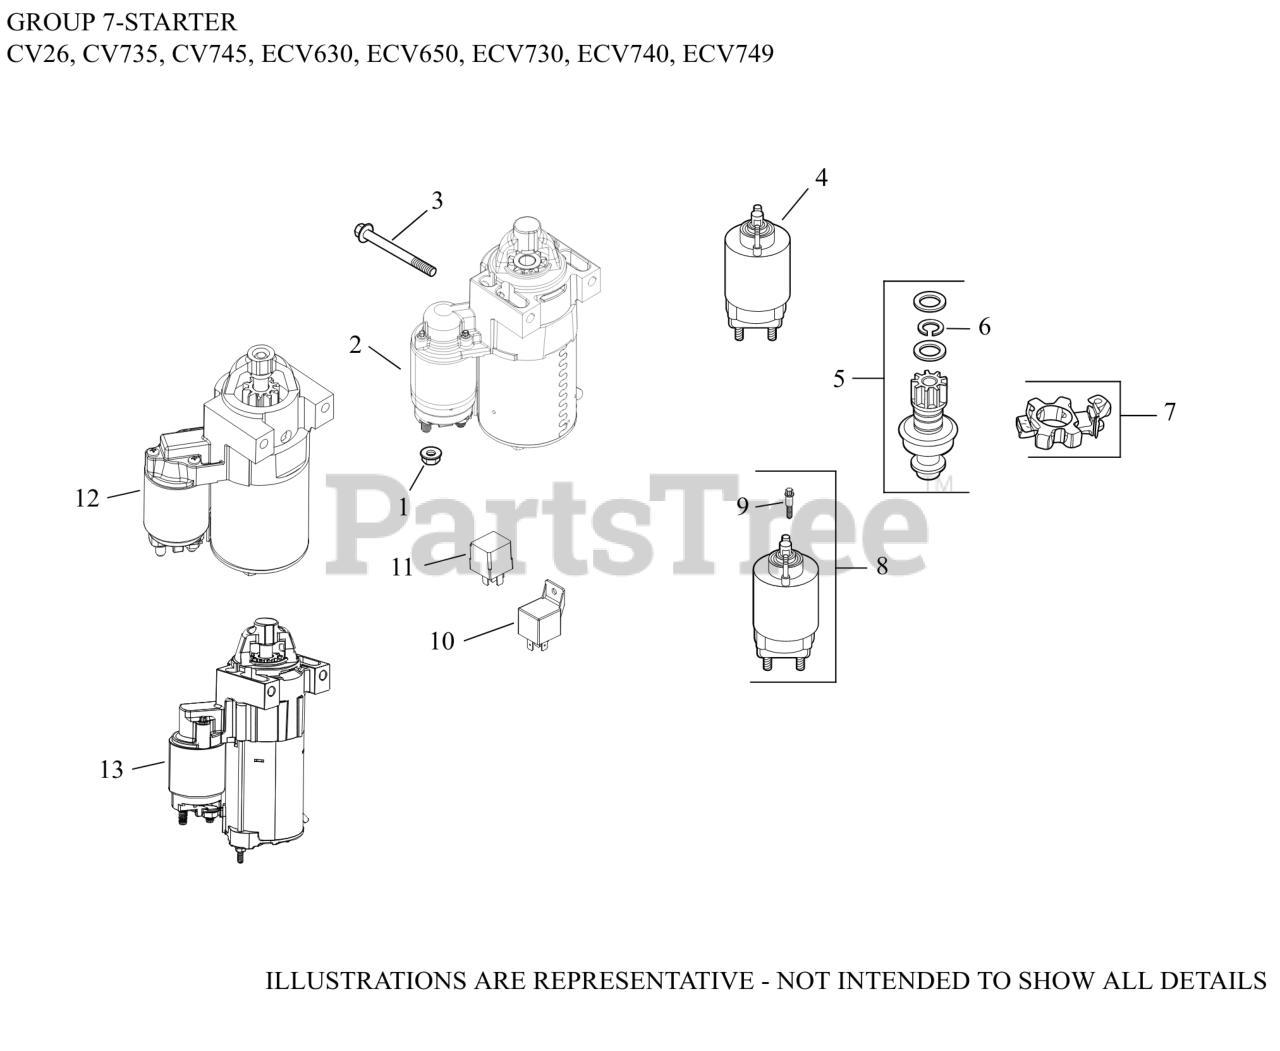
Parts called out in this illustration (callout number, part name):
1	NUT, FLG M8X1.25
2	STARTER, SOLENOID SHIFT-(#2509824S)
3	SCREW, FLG M8X1.25X80
